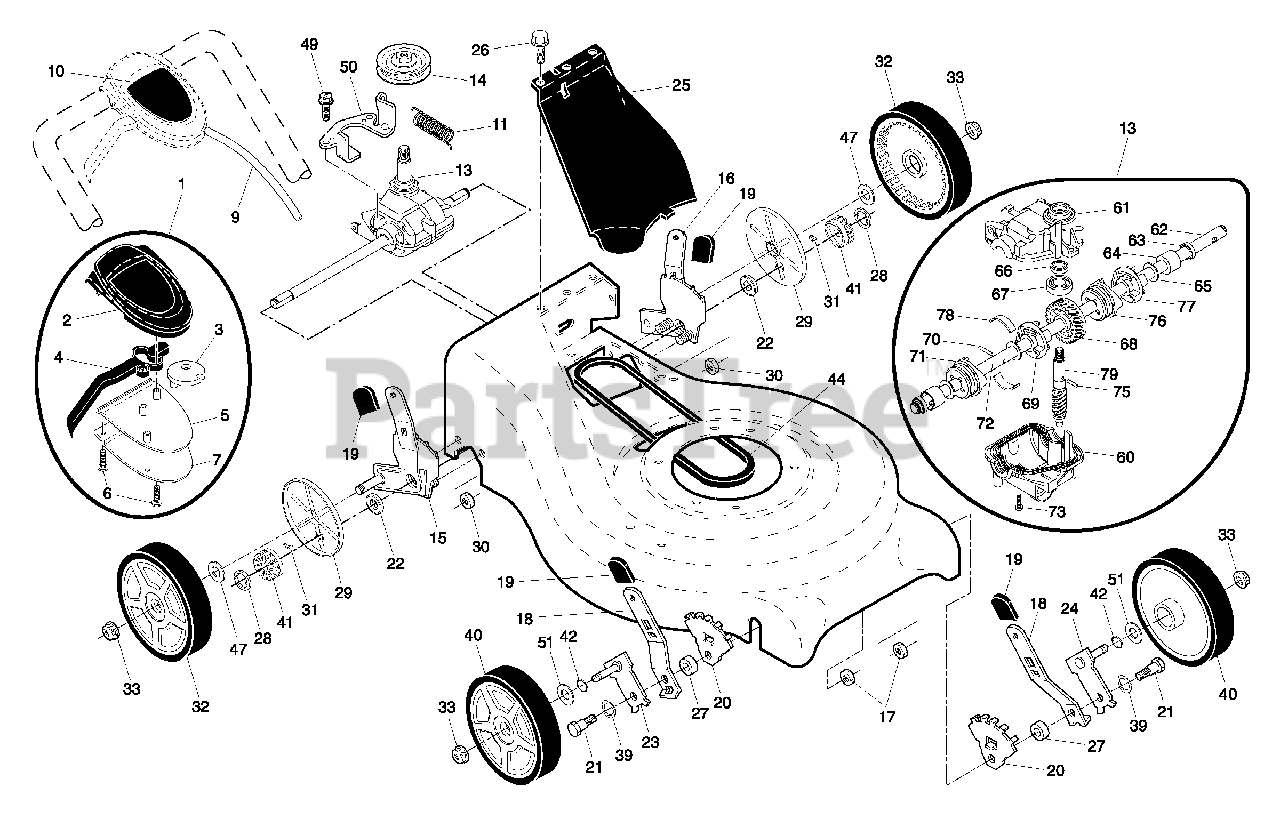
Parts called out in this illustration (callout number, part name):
1	Drive Control Assembly
2	Cover, Top, Drive Control
4	Lever, Drive Control
5	Cover, Bottom, Drive Control
6	Screw, Phillips Head #10 x 5/8
7	Mounting Bracket, Drive Control
9	Cable, Drive Control
10	Decal, Drive Control
13	Gear Case Assembly, Complete
14	Pulley, Drive
15	Kit, Wheel Adjuster Assembly, RH
16	Kit, Wheel Adjuster Assembly, LH
17	Nut, Hex
18	Spring Selector
19	Knob, Selector Spring
20	Bracket, Wheel Adjusting
21	Bolt, Shoulder, Hex Head
22	Bearing, Ball
23	Axle Arm Assembly, RH
24	Axle Arm Assembly, LH
25	Cover Drive
26	Screw, Threaded, Rolled #10-25 x 1/2
28	E-Ring 7/16
29	Cover, Dust, Wheel
30	Nut, Hex
32	Wheel & Tire Assembly, Rear
33	Nut, Hex, Flangelock 3/8-16
39	Washer, Curved, Cylindrical
40	Wheel & Tire Assembly, Front 8 x 2
47	Washer 1/2 x 1-1/2 x .134
49	Screw, Hi-Lo Thread #12 x 5/8
50	Belt Keeper
51	Washer, Flat 1/2
60	Case, Lower
61	Case, Upper
62	Long Shaft
63	Seal, Output Shaft
66	Seal, Worm Shaft
67	Bearing, Ball
68	Gear, 28 Teeth
69	Fixed Dog Clutch, LH
70	Pin, Output Shaft
71	Movable Dog Clutch, LH
72	Short Shaft
73	Screw, Case
75	Pin, Worm Shaft
76	Fixed Dog Clutch, RH
77	Movable Dog Clutch, RH
78	Spring, Leaf
79	Shaft, Worm
